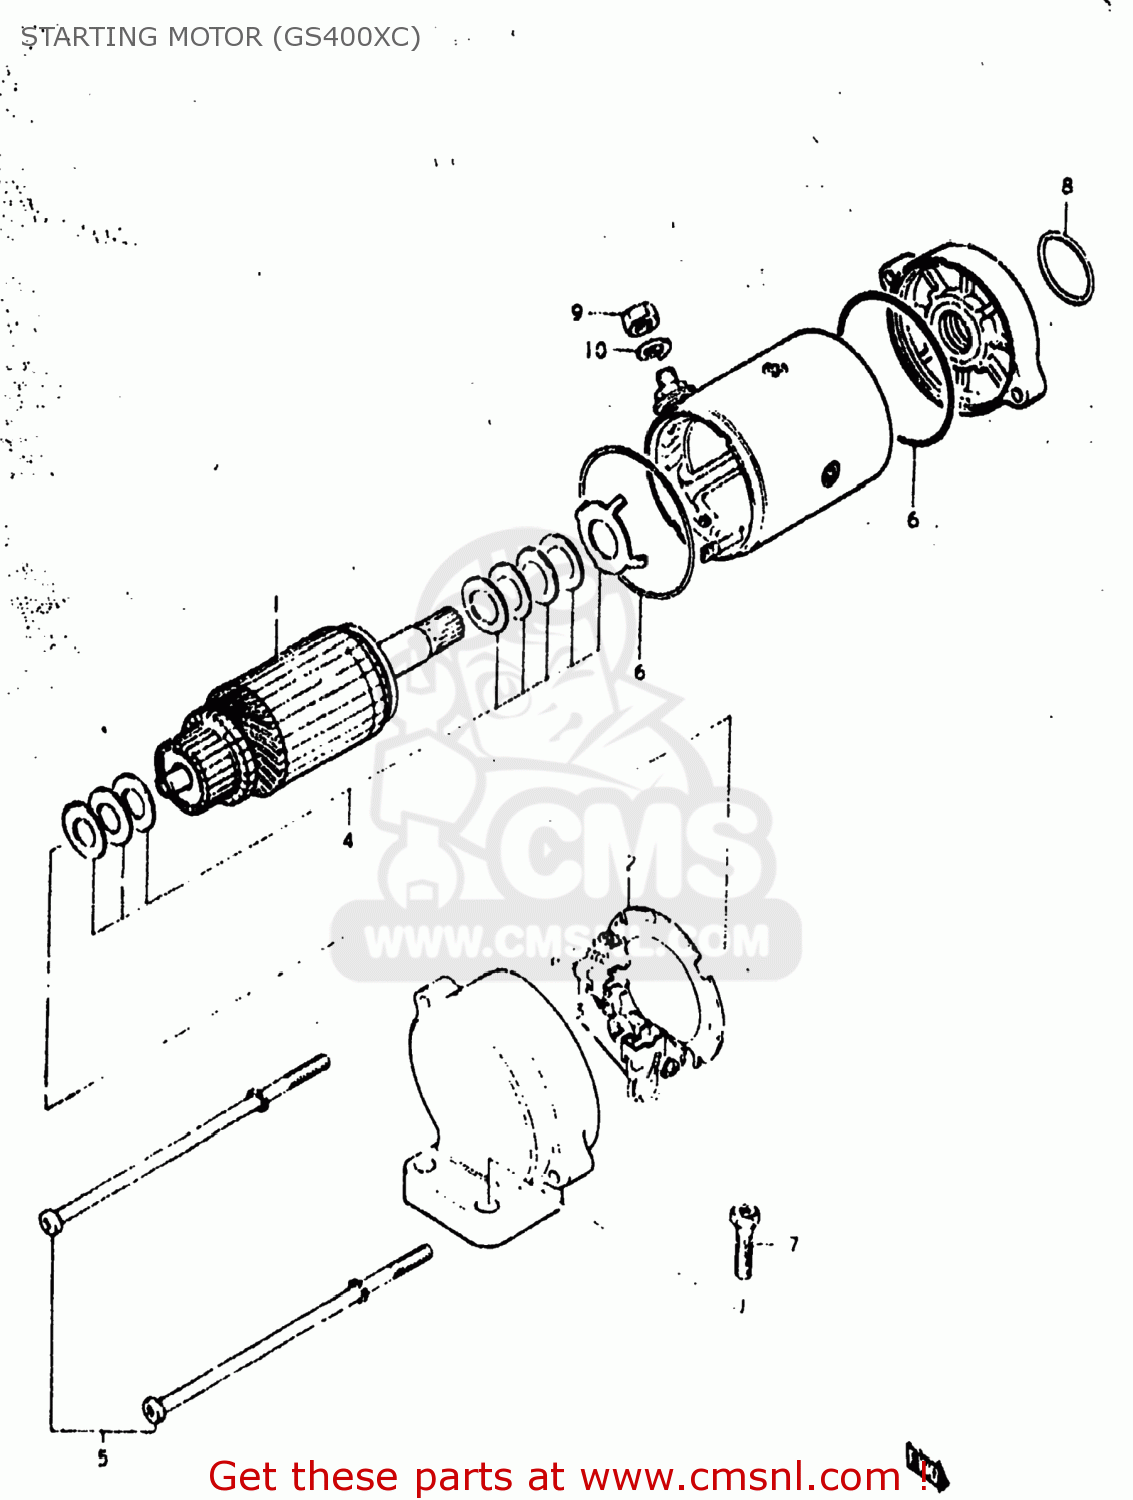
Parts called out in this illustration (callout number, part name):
1	ARMATURE
2	HOLDER ASSY
3	BRUSH SET
4	SHIM SET
5	BOLT,STARTING MOTOR HOUSING
6	O RING
7	SCREW
8	O RING(D:2,ID:24.5)
9	NUT 6MM
10	LOCK WASHER
